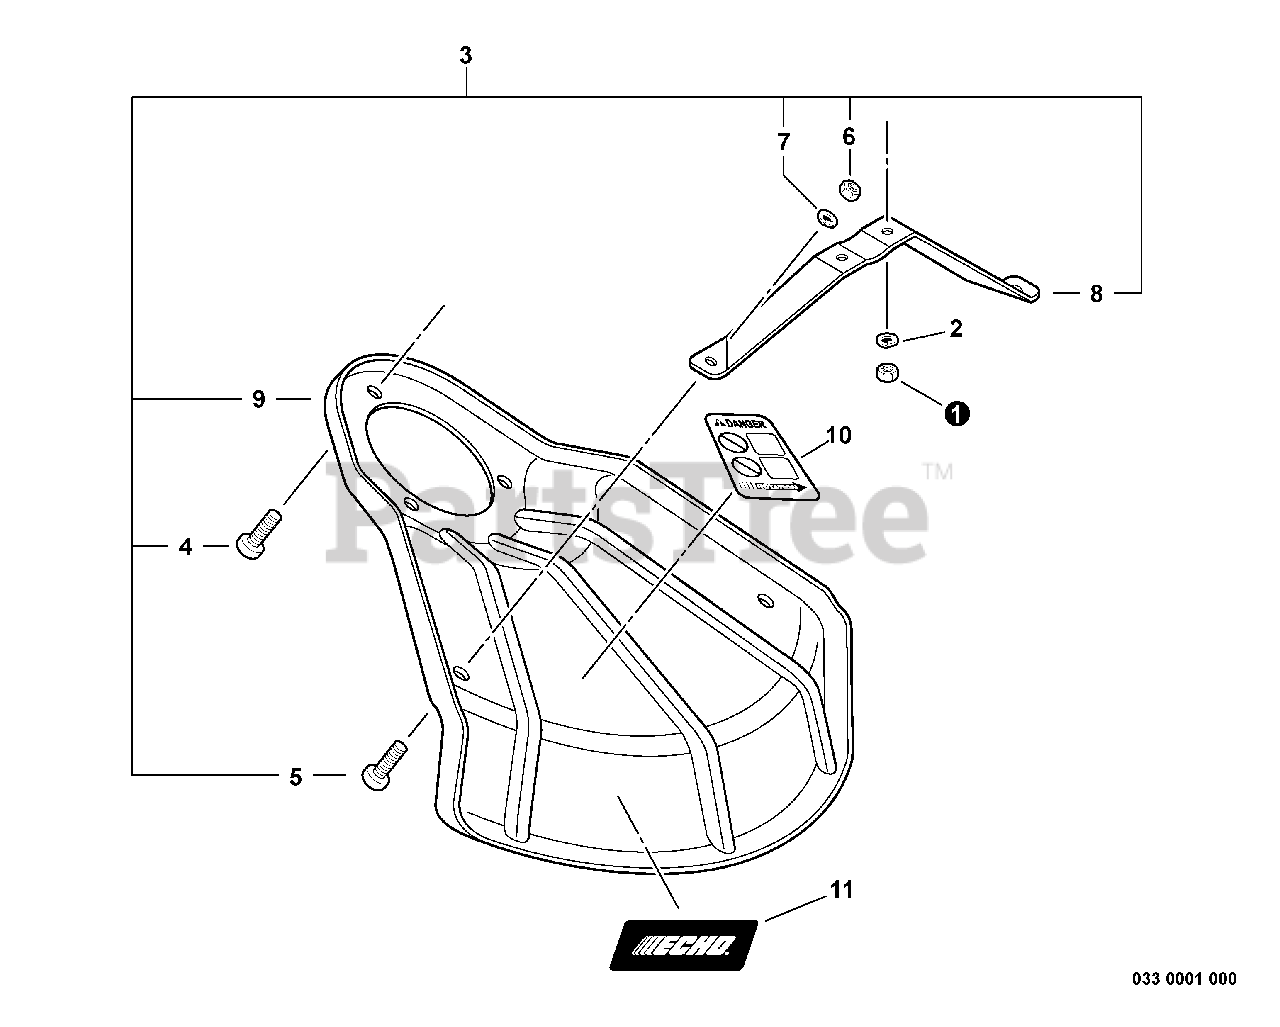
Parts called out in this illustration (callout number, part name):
2	LOCKWASHER - 5
3	DEBRIS SHIELD KIT - METAL
4	SCREW - 5X10
5	SCREW - 5X8
7	LOCKWASHER - 5
8	BRACKET, SHIELD
9	SHIELD, DEBRIS - METAL
10	LABEL - DANGER
11	LABEL - ECHO
